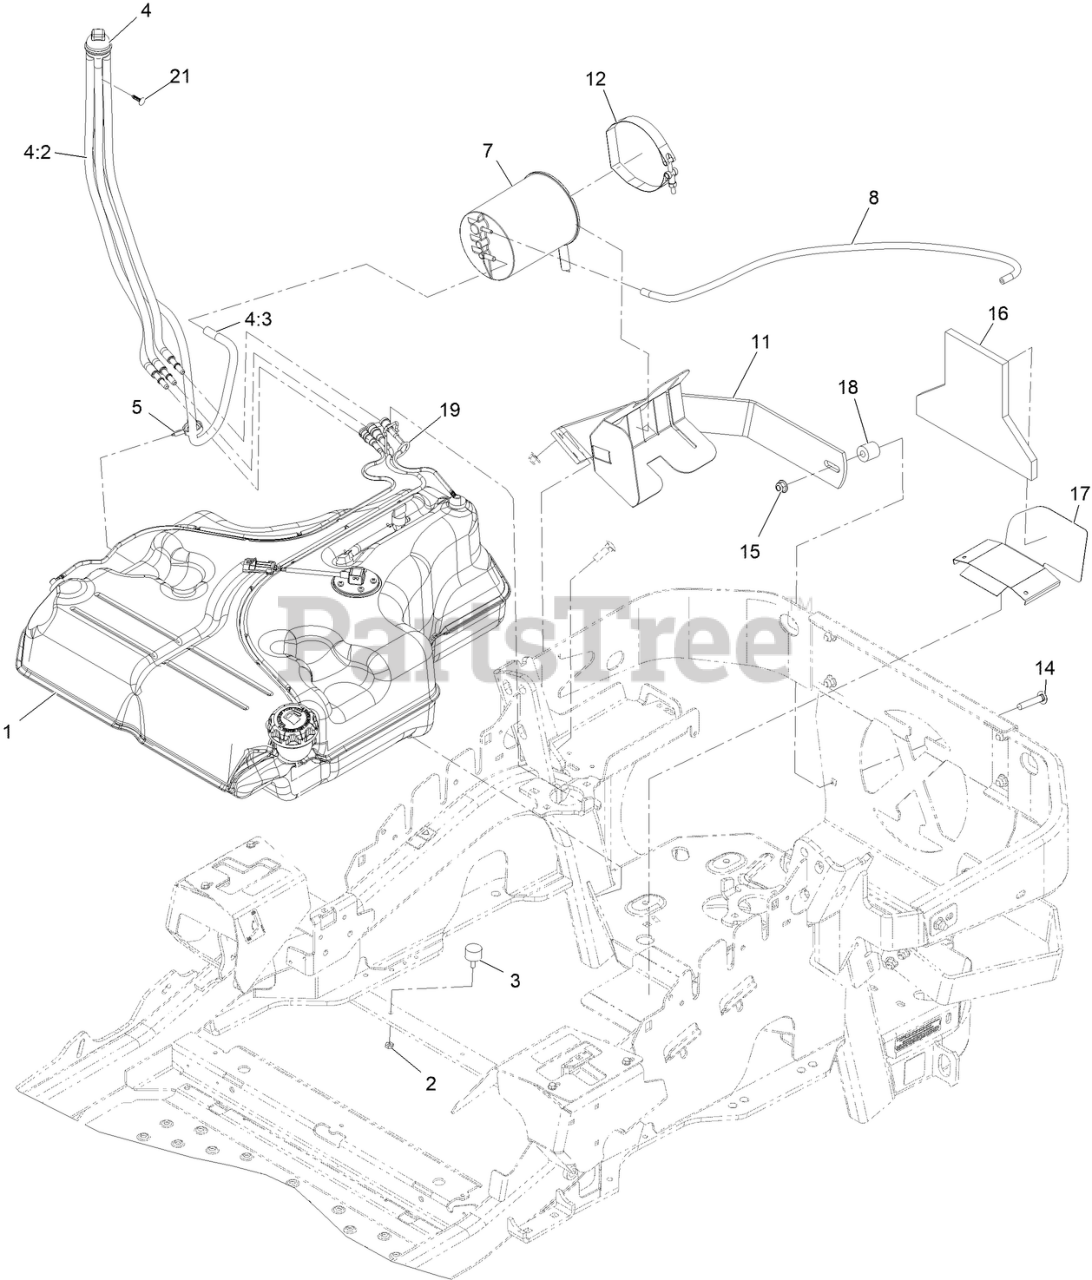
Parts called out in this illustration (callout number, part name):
1	FUEL TANK ASM
2	NUT-JAM
4	FUEL MANIFOLD VENT ASM
4:2	HOSE-FUEL
4:3	HOSE-FUEL
5	CLAMP-HOSE
7	CANISTER-CARBON, 1200CC
8	HOSE-FUEL
11	MOUNT-CANISTER
12	CLAMP, T-BOLT
14	BOLT-CARRIAGE
15	NUT-HF, NI
16	INSULATION-FOAM, FUEL TANK
17	GUARD-EXHAUST
19	RETAINER-LINE, VAPOR
21	PLUG-PLASTIC
